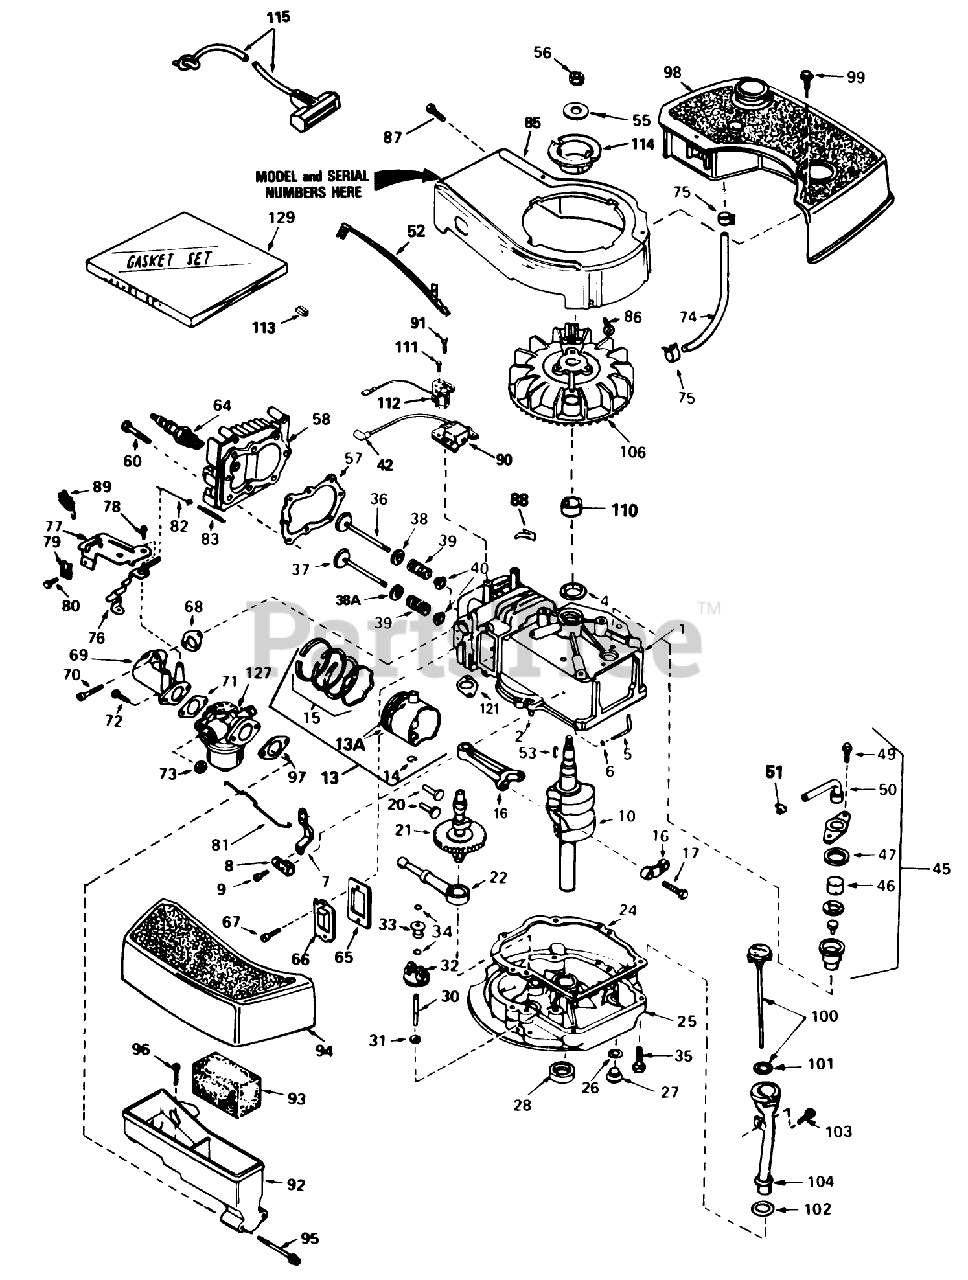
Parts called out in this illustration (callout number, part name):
1	Cylinder Assy. (Inc. #2 4)
2	Pin-Dowel
4	Seal-Oil
5	Rod, Governor (Incl. No. 36)
6	Washer-Flat
7	Governor Lever
8	Clamp-Lever, Governor
9	Screw
10	Crankshaft
13	Piston, Pin Ring Assy. (Std.) (Incl. Ref. #13A, 14 15)
13	Piston, Pin Ring Assy. (.010 oversize) (Incl. Ref. #13A, 14 15)
13	Piston, Pin Ring Assy. (.020 oversize) (Incl. Ref. #13A, 14 15)
13A	Piston Pin Assy. (Incl . Ref. . #14) (Std.)
13A	Piston Pin Assy. (Incl. Ref. #14) (.010 Oversize)
13A	Piston Pin Assy. (.020 oversize) (Incl. Ref. #14)
14	Ring-Retaining, Piston Pin
15	Ring Set (Std.)
15	Ring Set (.020" OS)
15	Ring Set (.010" OS)
16	Rod Assy., Connecting (Incl. Ref. #17)
17	Bolt-Rod, Connecting
20	Lifter-Valve
21	Camshaft(Mech.Comp. Release)
22	Oil Pump ASM
24	Gasket
25	Flange Assy.-Mounting (Incl. Ref. #26, 27, 28 31)
26	Gasket-Oil Drain
27	Plug Oil Drain
28	Seal Oil
30	Shaft-Governor
31	Washer-Flat
32	Governor Gear ASM
33	Spool-Governor
34	Ring-Retaining
35	Screw (1/4-20 x 1-1/4)
36	Valve, Intake (Std.) (Incl. Ref. #40)
36	Valve, Intake (1/32" oversize)(Incl. No. 40)
37	Valve, Exhaust (Std.)(Incl. No. 40)
37	Valve, Intake (1/32" oversize)(Incl. No. 40)
38	Seal Assy., Intake
38A	Cap-Upper Valve Spring
39	Spring-Valve
40	Cap-Valve, Spring
42	Cover-Spark Plug
45	Breather Assy. (Incl. Ref. #46 thru 51)
46	Element-Breather
47	Gasket-Breather
49	Screw (10-24 x 9/16)
50	Tube, Breaker
51	Clip, Breather
52	Wire-Ground
53	Key-Flywheel
55	Washer-Belleville
56	Nut-Flywheel
57	63573 GIL 42 SNWTHW
58	Head-Cylinder
60	Screw (5/16-18x1-1/2)
64	Spark Plug-Resistor (R J19 L M)
65	Gasket-Breather
66	Cover-Valve
67	Screw
68	Gasket-Intake
69	Pipe, Intake (Incl. No. 68)
70	Screw (1/4-20 x 1)
71	Gasket-Carburetor
73	Nut and Lock Washer (1/4-28)
74	Line-Fuel
75	Clamp-Line, Fuel
76	Lever Control
77	Control Assy., Speed (Incl. Nos, 76, 78 89)
78	Screw, Hex Washer Hd Shoulder Self-Tap
79	Conduit
80	Screw (10-32 x 3/8)
81	Link-Throttle
82	Link Governor Spring
83	Spring Governor
85	Housing Blower
86	Screw (1/4-20x19/32)
87	Screw (10-24 x 9/16)
88	Clip-Wire
89	Terminal
90	Solid State
91	Screw
92	Body Air Cleaner
93	Filer, Air
94	Cove, Air Cleaner
95	Screw Fil Hd.
96	Lever-Height Adjust (Rear)
97	Gasket-Air Cleaner
98	Tank-Fuel
99	Screw (10-32 x 35/64)
100	Dipstick, Oil (Incl. Ref. #101)(Twist Lock)
101	O-Ring
102	Gasket
103	Screw (10-32 x 1/2)
104	Tube-Oil Fill
106	Flywheel
110	Spacer
111	Screw (8-32x27/64)
112	Coil, Alternator
113	Terminal
114	Hub-Starter
115	Rope Assy., Starter
121	Gasket Exhaust
127	Carburetor (Incl. Ref. #71)
129	Gasket Set
